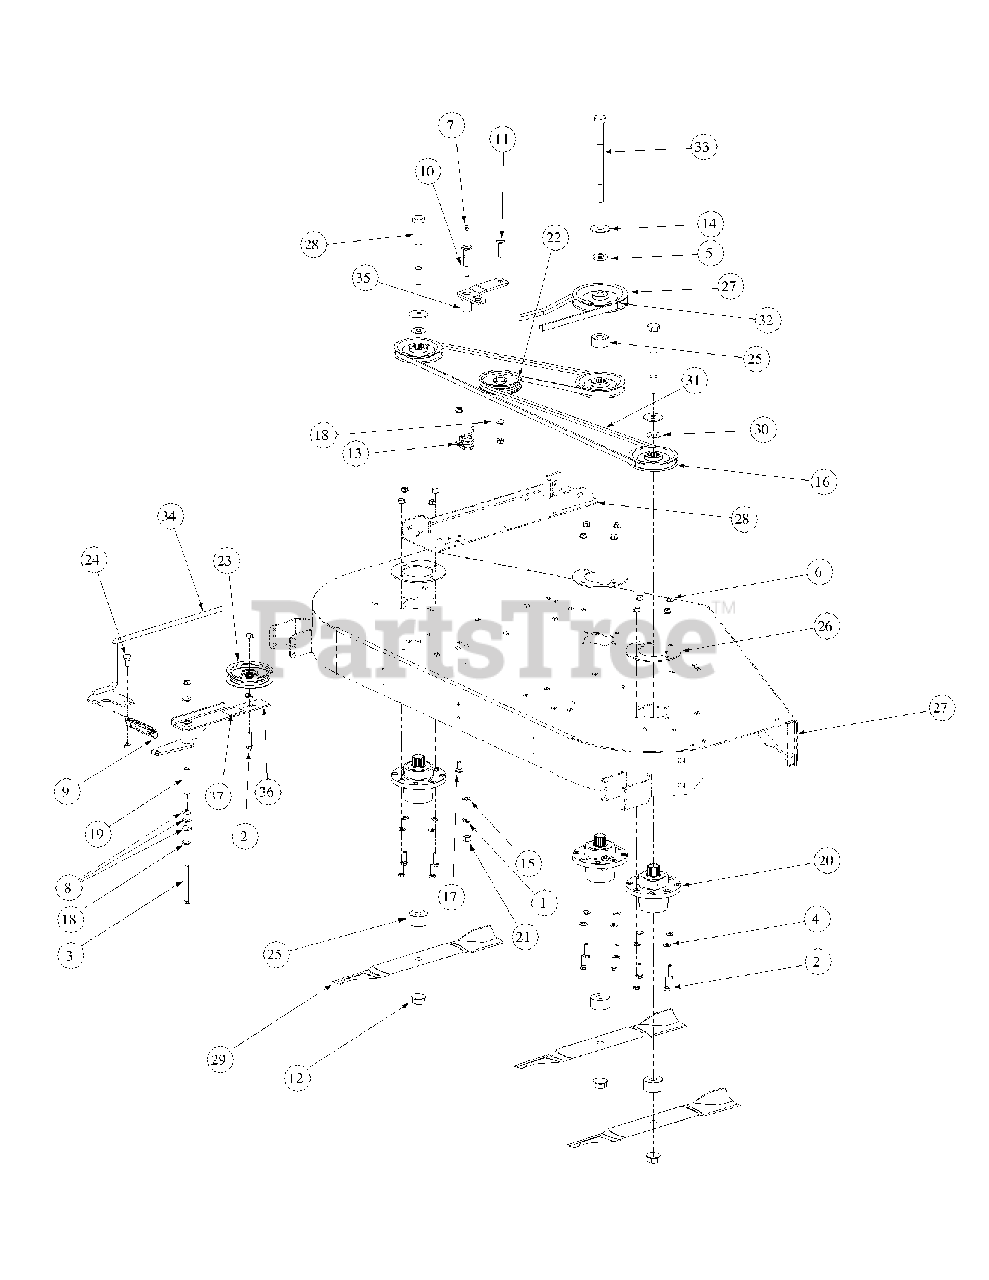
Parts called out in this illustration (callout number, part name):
1	Lock Washer, 7/16
2	Hex Cap Screw, 3/8-16 x 1-1/4
3	Hex Cap Screw, 3/8-16, 4.00
4	Flat Washer, 3/8
5	Caster Spacer
6	Flange Lock Hex Nut, 3/8-16
7	Grease Fitting, 1/4-28 x 3/16
8	Idler Washer
9	Extension Spring, 1.0 x OD x 5.125
10	Shoulder Screw, 7/16-14
11	Hex Carriage Screw, 3/8-16, 1.75
12	Flange Hex Nut, 3/4-16
13	Torsion Idler Spring
14	Flat Washer, .781 ID 2.00 OD, .105
15	Flat Washer, .469 ID, .875 OD, .105
16	V-Pulley, 5.00 OD
17	Carriage Bolt, 3/8-16 x 1
18	Flat Washer, .406 ID, 1.0 OD, .105
19	Spacer, .39 ID x .625 OD x 2.75
20	Aluminum Spindle Assembly
21	Hex Nut, 7/16-14
22	Flat Pulley
23	Idler Pulley, 4.06 OD
24	Shoulder Screw, .50 x .27 Lg., 3/8-16
25	Spacer, .760 ID x 2.00 OD x 1.1
26	Aluminum Spindle Support Plate
27	V-Pulley, 5.774 OD
28	Hex Cap Screw, 3/4-16, 7.00
29	Hi-Lift Blade, 21.0, 0.756 ID
30	Spacer .812 ID x .268 LG
31	V-Belt, A Section x 122.3
32	V-Belt, B Section x 91.2
33	Hex Cap Screw, 3/4-16, 9.00
34	Spring Tension Rod Assembly
35	Idler Arm Assembly, Deck Spindle
36	Idler Arm Assembly, Flat Top Bearing
36	Bearing Sleeve
37	Decal, Idler Location
